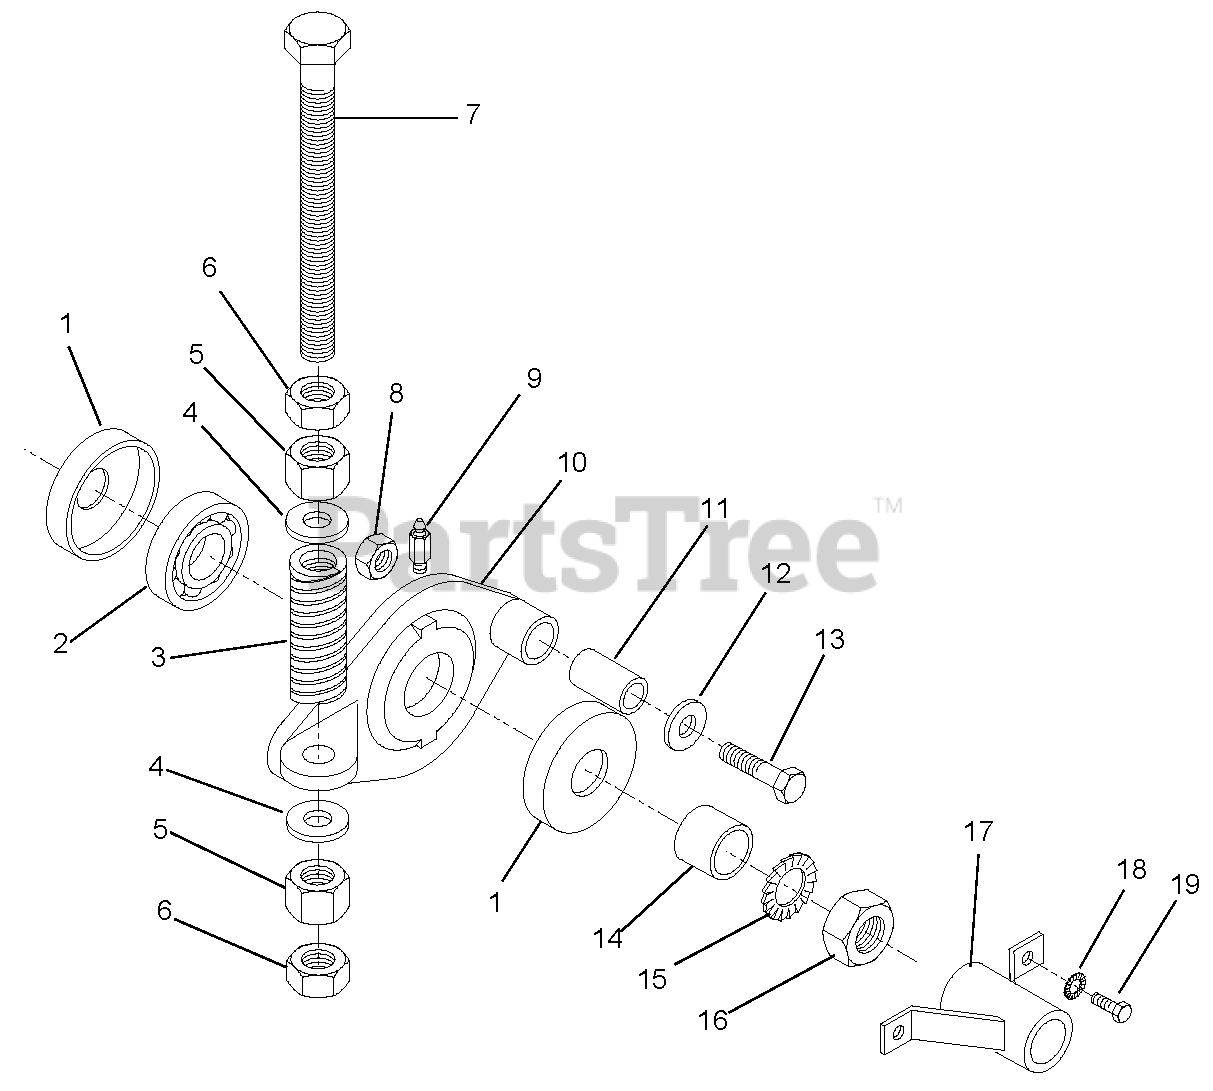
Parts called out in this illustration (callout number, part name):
1	Seal, Oil
3	Spring, Compression
4	Washer, Flat .625 SAE
5	Nut, Hex .625-18
6	Nut, Jam .625 NF CP
7	Cap Screw, Hex Head .625 x 8 NF
8	Nut, Jam .437
9	Fitting, Grease .25-28
10	Housing, Reel Bearing
11	Housing, Pivot Bushing Bearing
12	Washer, Flat .375
13	Cap Screw, Hex Head .375 – Modified
14	Spacer, Reel End
15	Washer, Star Lock, .75 External Tooth
16	Nut, Jam .75 NF
17	Weldment, Safety Cup
18	Washer. Star Lock .375 External Tooth
19	Cap Screw, Hex Head .375-16 x .50
